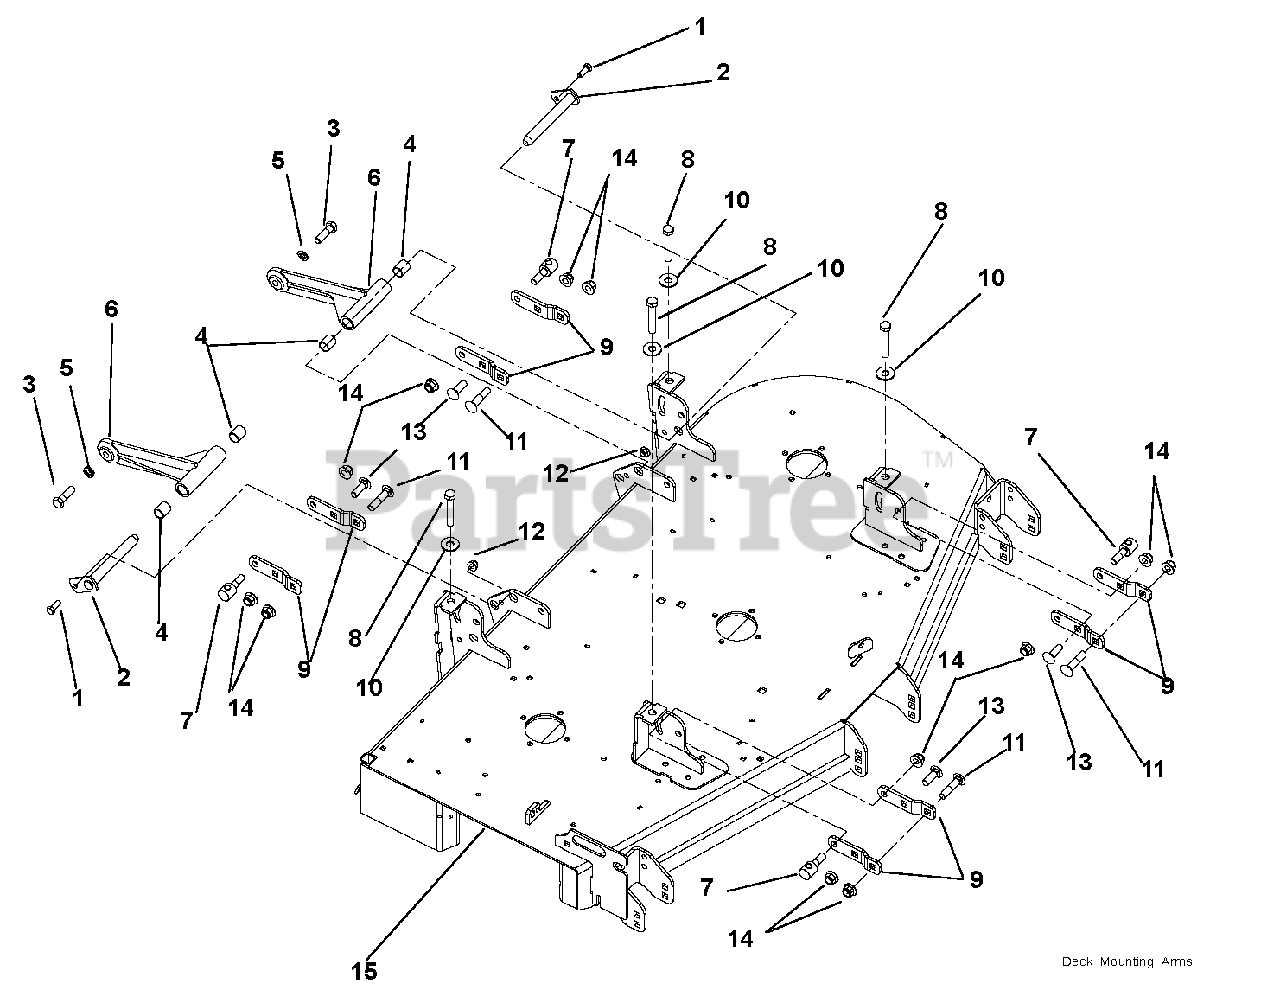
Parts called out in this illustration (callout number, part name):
1	Bolt, Hex .38-16 x 1.00
2	Weldment, Mower Mounting Pin
3	Bolt, Hex .50-13 x 1.75 Grade 5 EP80
4	Bearing, .75 x .875 x 1.00
5	Washer, Locking .50 x .125 Regular
6	Deck Pusher Arm Weldment, Black
7	Trunnion, .50-13
8	Bolt, Hex .50-13 x 3.00
9	Bracket, Deck Leveling
10	Washer, Flat Steel .563 x 1.38 x .109
11	Bolt, Round Head Square Neck .50-13 x 2.25
12	Nut, Locking Nylon Flange .38-16
13	Bolt, Round Head Square Neck .50-13 x 1.50
14	Nut, Locking Nylon Flange .50-13
15	Weldment, 48" Side Discharge Deck (991079, 095, 102)
